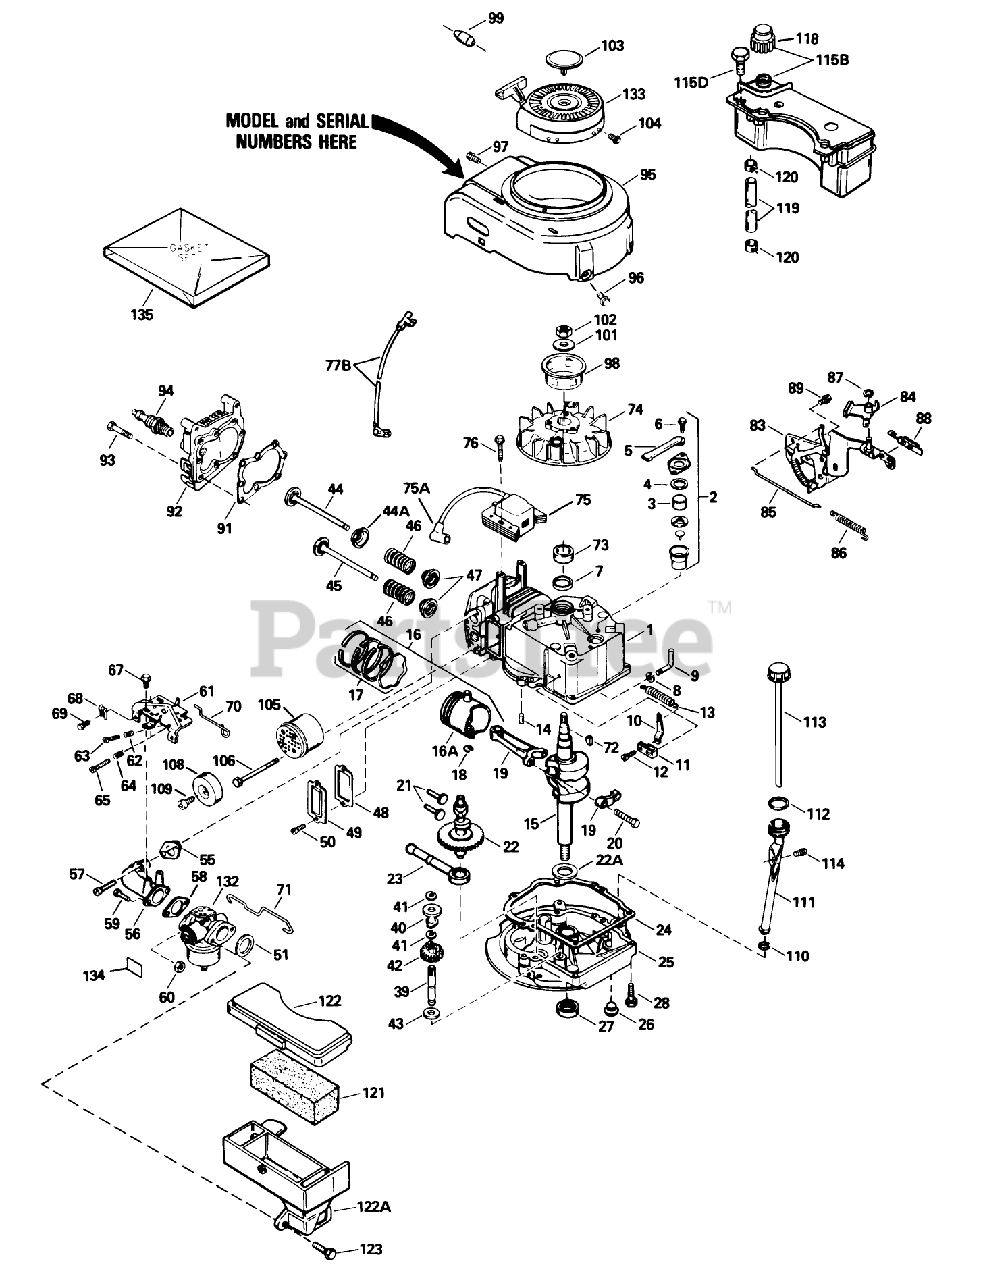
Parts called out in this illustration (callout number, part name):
1	Cylinder Assy. (Incl. #24)
2	Breather Assy. (Incl. Ref. #46 thru 51)
3	Element-Breather
4	Gasket-Breather
5	Tube, Breaker
6	Screw (10-24 x 9/16)
7	Seal-Oil
8	Washer-Flat
9	Rod, Governor (Incl. No. 36)
10	Governor Lever
11	Clamp-Lever, Governor
12	Screw
13	Spring Governor
14	Pin-Dowel
15	Crankshaft
16	Piston-Pin Ring Assy. (Std.)(Incl. Ref. #16A, 17 18)
16	Piston-Pin Ring Assembly (.010 oversize)(Incl. Ref. #16A, 17 18)
16	Piston, Pin Ring Assy. (.020 Oversize)(Incl. Ref. #13A, 14, 15)
16A	Piston Pin Assy. (Std.)(Incl. Ref. #14)
16A	Piston Pin Assembly (.010 oversize)(Incl. Ref. #18)
16A	Piston Pin Assy. (.020 Oversize) (Incl. Ref. #14)
17	Ring Set-Piston (Std.)
17	Ring Set, Piston(.0100versize)
17	Ring Set (.020" OS)
18	Ring-Retaining, Piston Pin
19	Rod Assy., Connecting (Incl. Ref. #17)
20	Bolt-Rod, Connecting
21	Lifter-Valve
22	Camshaft(Mech.Comp. Release)
22A	Washer-Thrust
23	Oil Pump ASM
24	Gasket
25	Flange-Mounting (Incl. Ref. #26, 27 39)
26	Plug Oil Drain
27	Seal-Oil
28	Screw (1/4-20 x 1-1/4)
39	Shaft-Governor
40	Spool-Governor
41	Ring-Retaining
42	Governor Gear ASM
43	Washer
44	Valve, Intake (Std.) (Incl. Ref. #40)
44	Valve, Intake (1/32" oversize)(Incl. No. 40)
44A	Seal Assy., Intake
45	Valve, Exhaust (Std.)(Incl. No. 40)
45	Valve, Intake (1/32" oversize)(Incl. No. 40)
46	Spring-Valve
47	Cap-Valve, Spring
48	Gasket-Cover, Valve
49	Cover-Valve
50	Screw
51	Gasket-Cleaner, Air
55	Gasket-Intake Pipe
56	Pipe-Intake (Incl. Ref. #59)
57	Screw (1/4-20 x 1)
58	Gasket
60	Nut and Lock Washer (1/4-28)
61	Control Assy.-Remote Speed (Incl. Ref. #69 thru 72 76)
62	61709/GIL1515A/95-5
63	Screw
64	Spring-Compression
65	Screw
67	Screw (10-24 x 9/16)
68	Conduit
69	Screw (10-32 x 3/8)
70	2035A67 ADD.ASSEMBL
71	Link-Throttle
72	Key-Flywheel
73	Spacer
74	Flywheel
75	Solid State
75A	Cover-Spark Plug
76	Screw
77B	Ground Wire
83	Bracket-S.E. Brake
84	Lever-Brake
85	Link-Control
86	Spring-Extension
87	Ring-Retaining
88	Terminal
89	Screw (1/4-20 x 3/8)
91	Gasket-Cylinder Head
92	Head-Cylinder
93	Screw (5/16-18x1-1/2)
94	Spark Plug-Resistor (R J19 L M)
95	Housing-Blower
96	Screw (1/4-20 x 1/2)
97	Screw (10-24 x 9/16)
98	Hub-Starter
99	Retainer-Starter Rope
101	Washer-Belleville
102	Nut-Flywheel
103	Plug Starter
104	Screw, Hex Hd.
105	Muffler (Incl. Ref. #122)
106	Screw
108	Cover-Muffler
109	Screw (8-32 x 3/8)
110	Gasket
111	Oil Fill Tube
112	O-Ring
113	Dipstick
114	Screw (10-32 x 1/2)
115B	Tank Assembly-Fuel (Incl. Ref. #102)
115D	Screw (10-32 x 35/64)
118	Cap-Fuel
119	Line-Fuel
120	Clamp-Line, Fuel
121	Filter-Air Cleaner
122	Cover Air Cleaner
122A	Body Air cleaner
123	Screw
132	Carburetor (Incl. Ref. #83)
133	Starter-Rewind
134	Decal-Primer
135	Gasket Set (Incl. Items Marked *)
